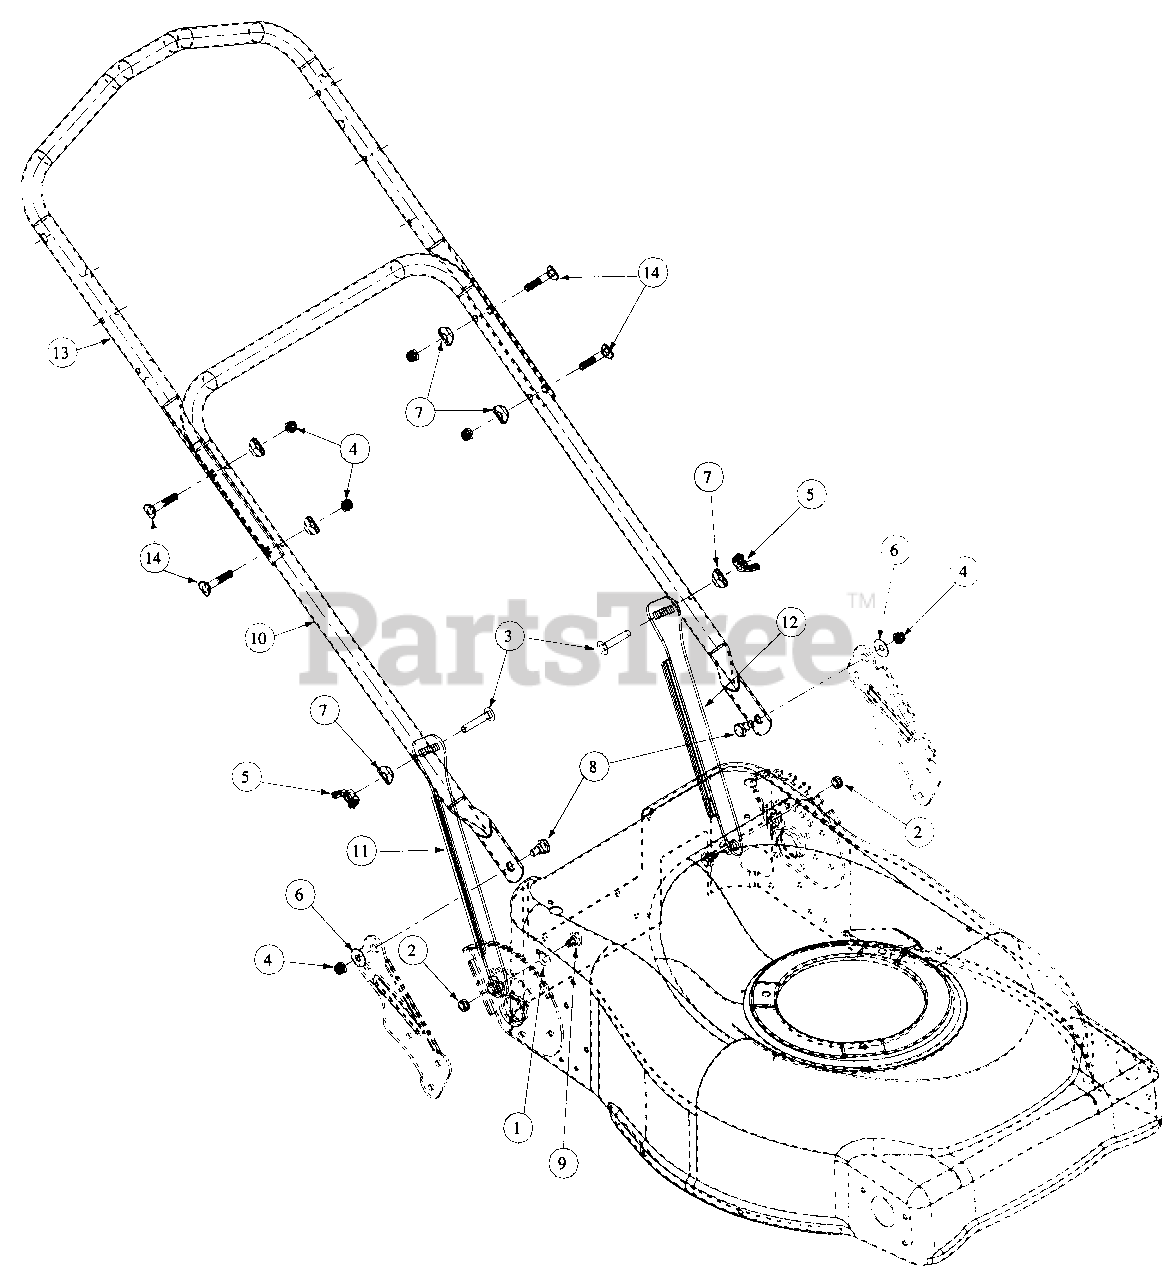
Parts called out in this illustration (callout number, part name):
1	Thrust Washer
2	Nut, Lock, 5/16-18,
3	Bolt Carriage, 5/16-18, 1.75
4	Hex Nut, 5/16-18
5	Wing Nut, 5/16-18
6	Belle Washer, .325 x .930 x .045
7	Shoulder Washer, .320 ID x .93 OD
8	Shoulder Screw, .435 x .350, 5/16-18
9	Shoulder Screw, .437 x 1.62 LG
10	Handle, Lower, 1.0"
11	Strut, 3 Position Handle, Right hand
12	Strut, 3 Position Handle, Left hand
13	Upper Handle, 1.0", Self Propelled
14	Carriage Bolt, 5/16-18 X 2.0 CRVD
